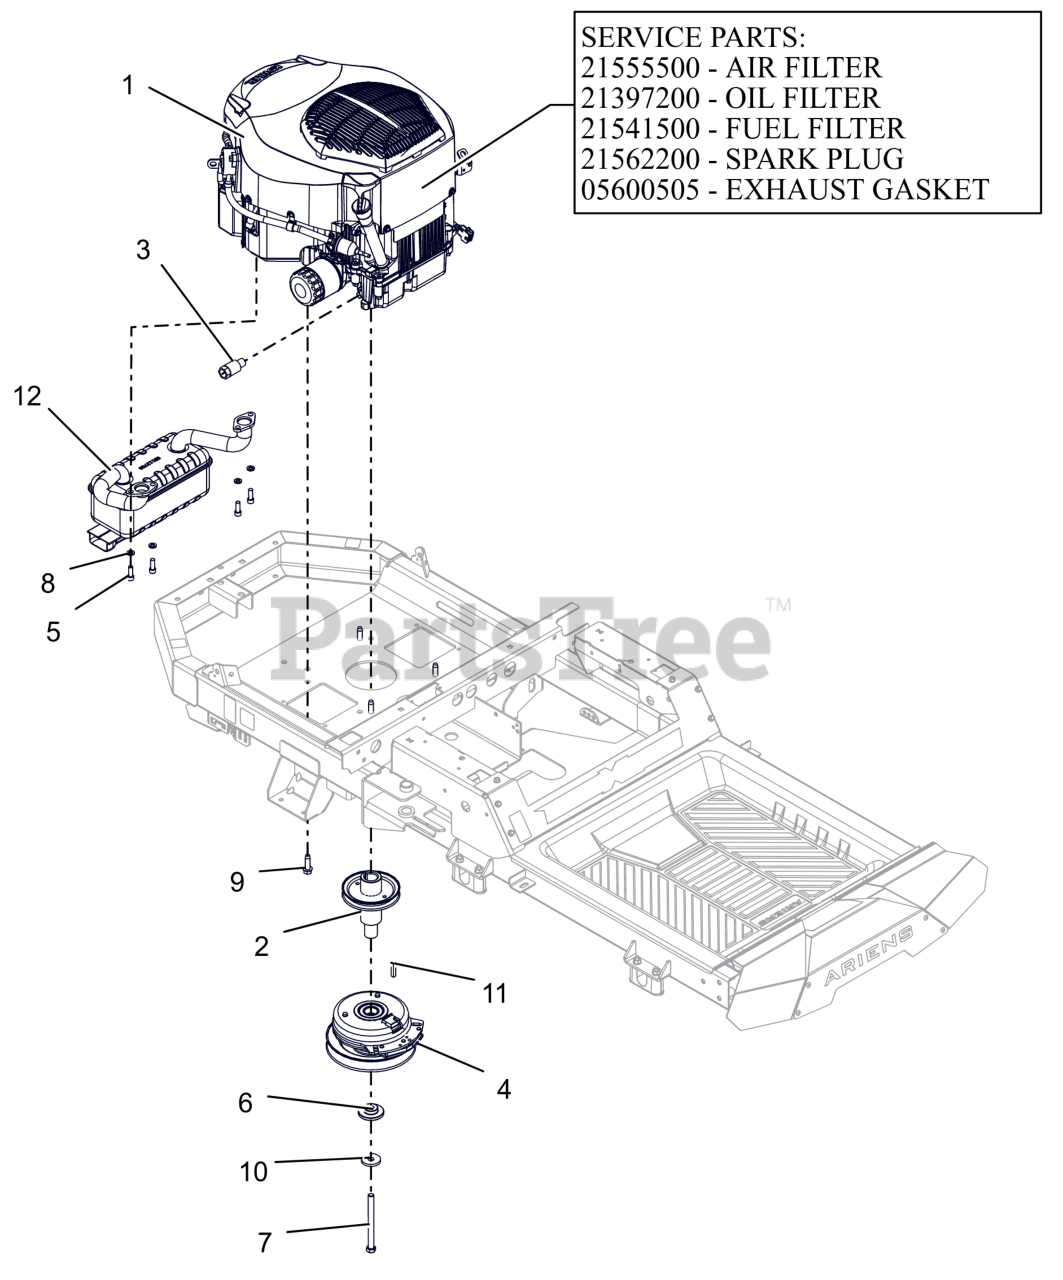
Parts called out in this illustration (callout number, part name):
1	ENGINE, KOHLER TWIN - 25HP
1	AIR CLEANER, KOHLER
1	FILTER, OIL - KOH CV20
1	FILTER, FUEL
1	PLUG, SPARK (RFI)
1	GASKET, MUFFLER COURAGE TWIN
2	WLDMT, DRIVE SHEAVE (LG XL)CZC
3	DRAIN, OIL
4	CLUTCH,105FTLB MONOPOLE 6.83"
5	SCR-CAP .31-18X.88 S/HD G8 ZCC
6	BSHG-FLG .469X1.06X.574X2.0
7	BLT-HEX.438-20X5 GR8 YZ NYTORQ
8	WSHR,LK-REG .312X.078 ZCC
9	SCR,TAP .375-16X1.25HWH TR ZCC
10	WASHER, 7/16" SPRING DISK
11	KEY-SQ .25 X 1.25 X .25 SAE
12	MUFFLER, KOHLER
